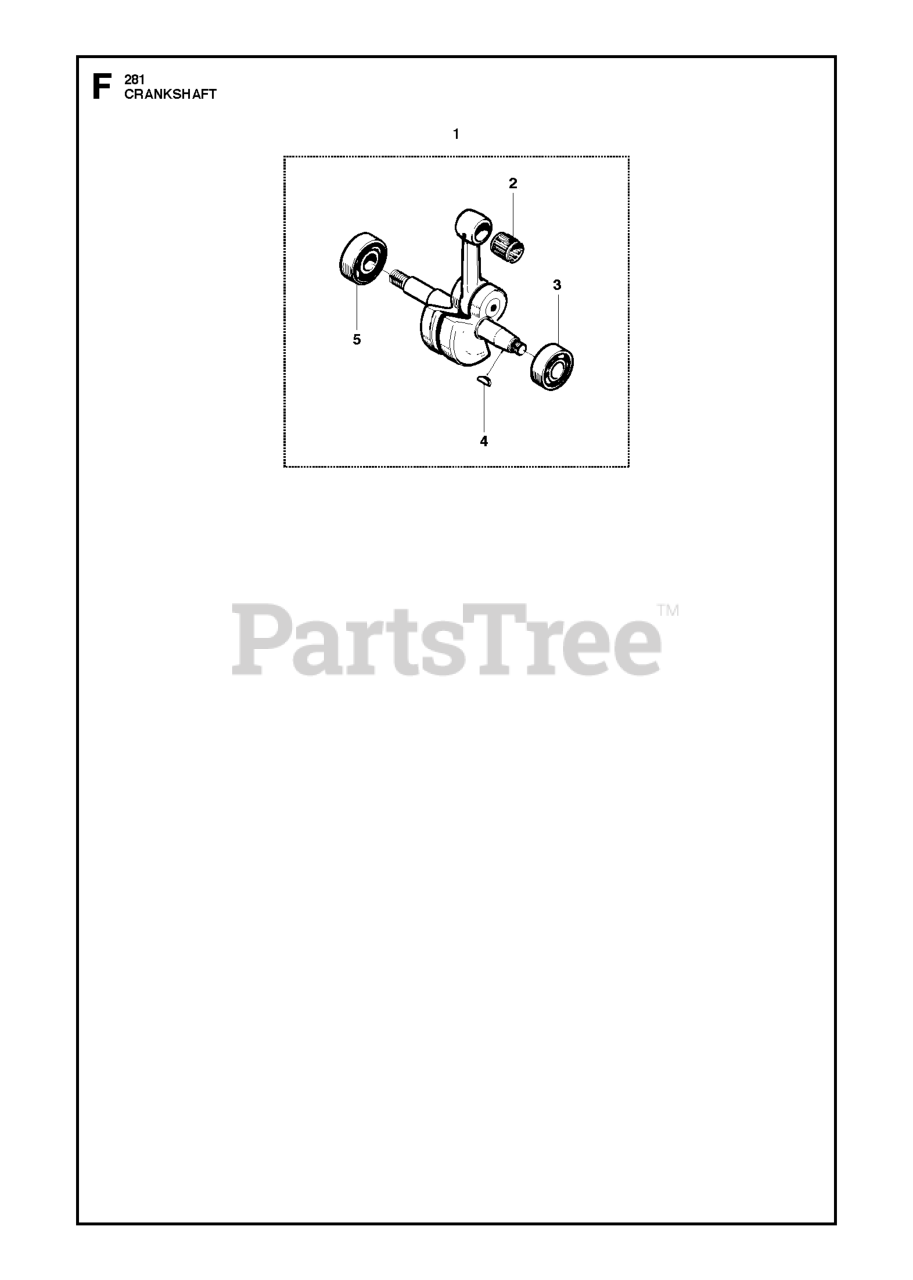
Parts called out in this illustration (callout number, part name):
1	CRANKSHAFT
2	SUPPORT BUSHING
3	BALL BEARING 6203 C3
4	WOODRUFF KEY
5	BALL BEARING 6203 C3
